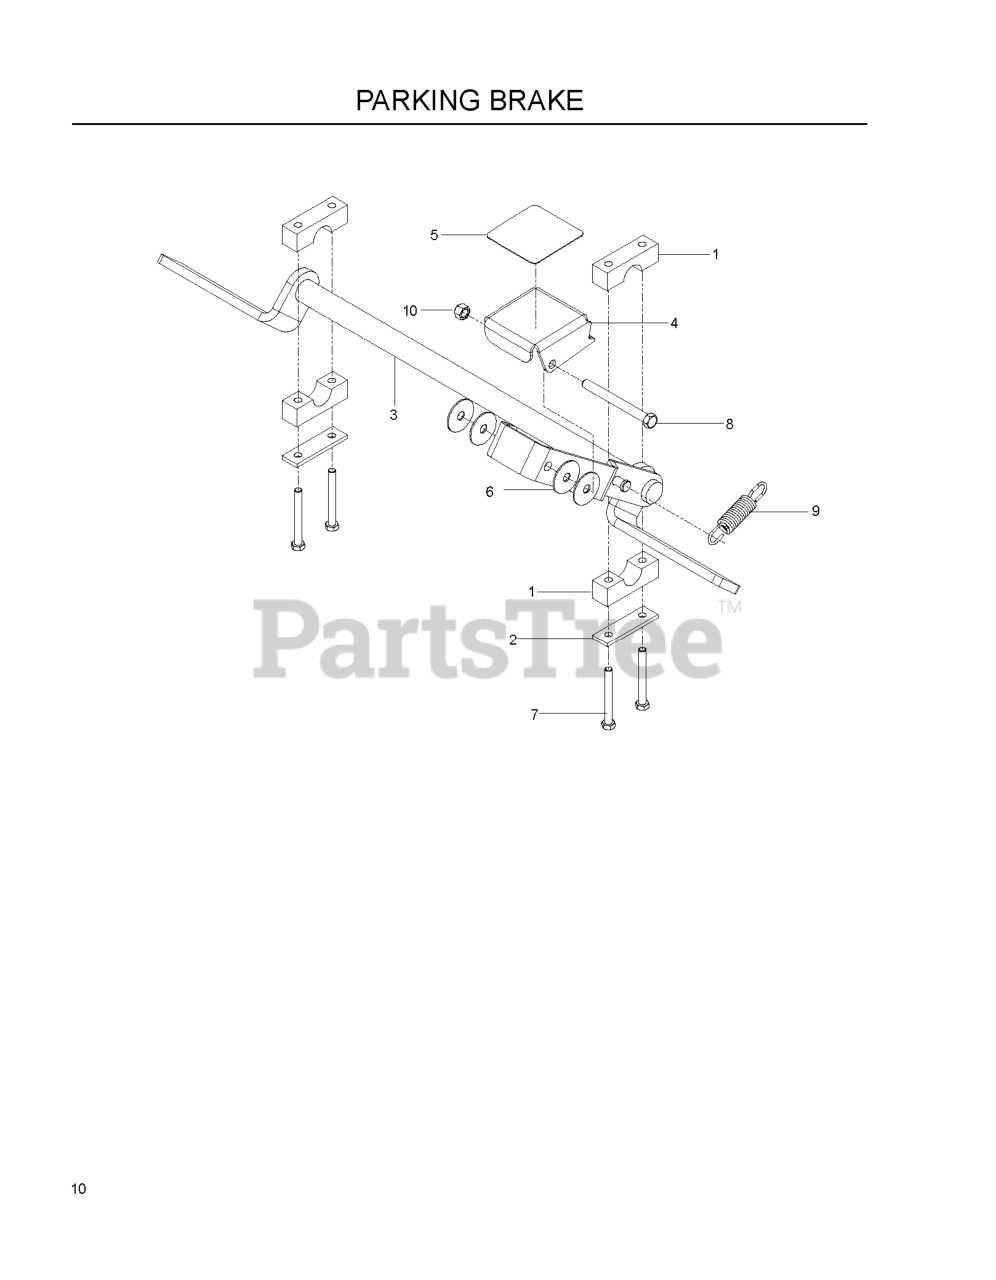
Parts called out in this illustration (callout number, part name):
1	PILLOW BLOCK
2	REINFORCEMENT BAR
3	PARK BRAKE
4	PEDAL, BLACK
5	ANTI-SKID PAD
6	WASHER, FRICTION
7	HCS 5/16C X 2-3/4
8	HCS3/8-16.X
9	SPRING, EXTENSION
10	NUT 3/8-16 NYLOC
